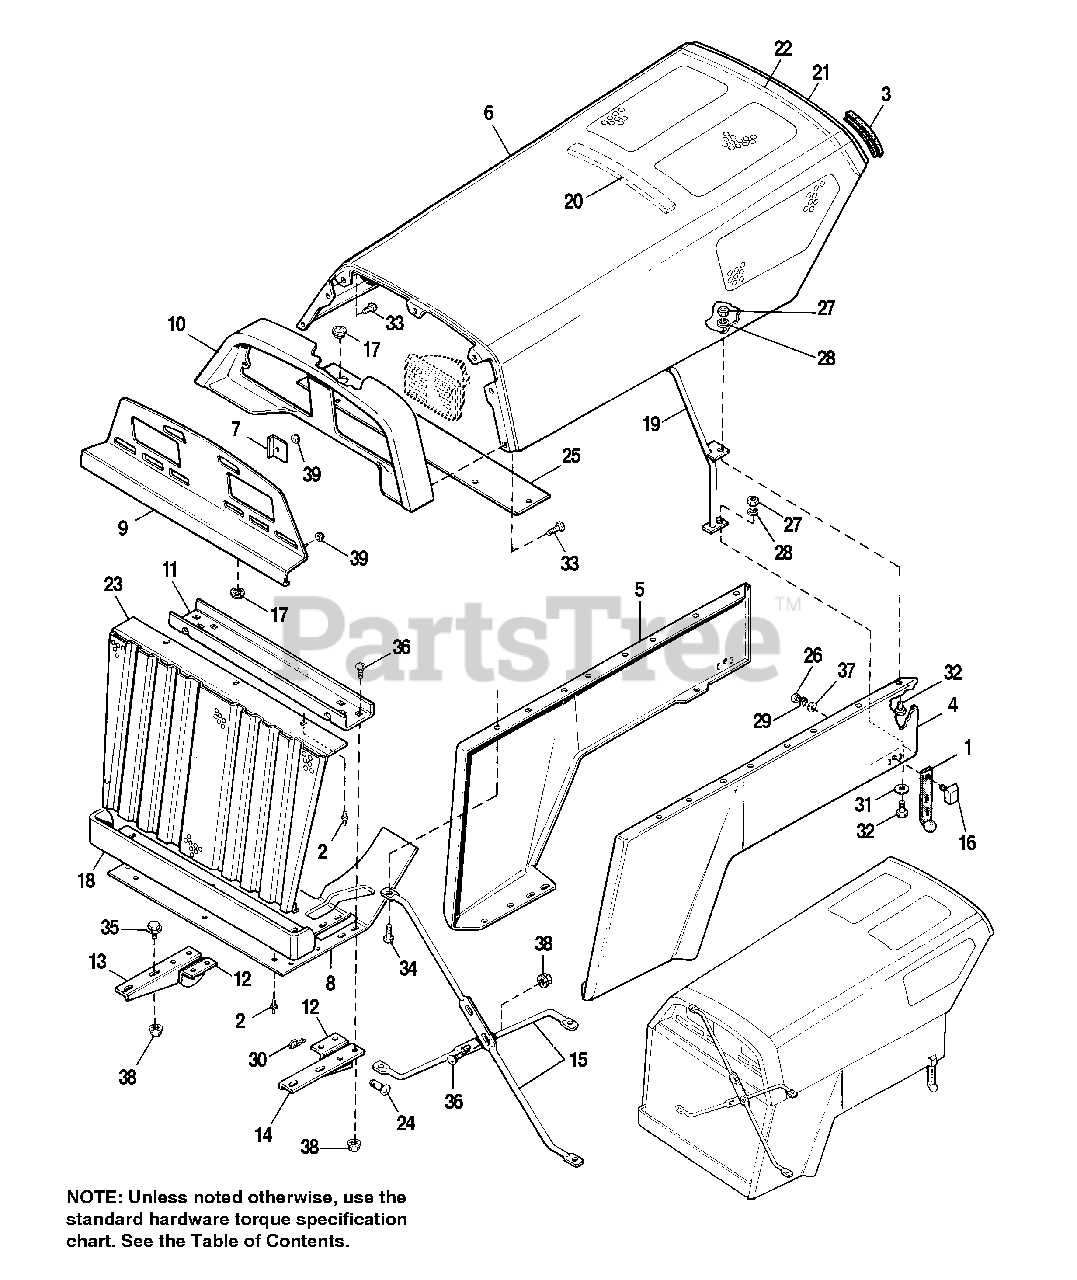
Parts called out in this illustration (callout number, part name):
1	STRAP, Hood
2	RIVET, Pop, 3/16
3	MOULDING, Hood
4	PANEL, Side, LH.
5	PANEL, Side, RH
7	CLIP, Headlamps, Mounting
8	SHIELD, Heat
9	HEADLAMP INSERT ASSY.
10	FRAME, Headlamps
11	SUPPORT, Stop, Hood
12	HINGE, Hood, Inner
13	HINGE, Hood, Outer, RH
14	HINGE, Hood, Outer, LH
15	BRACE, Hood, Front
16	COVER ASSY., Hood Strap
17	BUSHING, Universal
18	BUMPER ASSY.
19	SUPPORT ROD ASSY., Hood
20	SEAL, Hood Support
21	DECAL, Hood, Rear
22	SEAL, Hood, Rear
23	SCREEN ASSY., Grille
24	PIN, Lock (Clevis)
25	SHIELD, Muffler
26	NUT, Hex, #10-24
27	NUT, Hex, 1/4-20
28	LOCKWASHER, 1/4
29	LOCKWASHER, #10
30	PIN, Quick, 3/32 x 1-7/8
31	WASHER, Plain,1/4 x 5/8 x 3/64
32	CAPSCREW, Hex Hd., 1/4-20 x 1/2
33	SCREW, Hex, Taptite, 1/4-20 x 1/2
34	SCREW, Hex, Thd. Form, #14-3/4
35	SCREW, Hex, Flange, Whizlock, 1/4-20 x 3/4
36	CARRIAGE BOLT, 1/4-20 x 3/4
37	WASHER, 13/64 I.D. x 3/4
38	NUT, Hex, Flange Whizlock, 1/4-20
39	PAL NUT, Hex, Lock, #10-24
